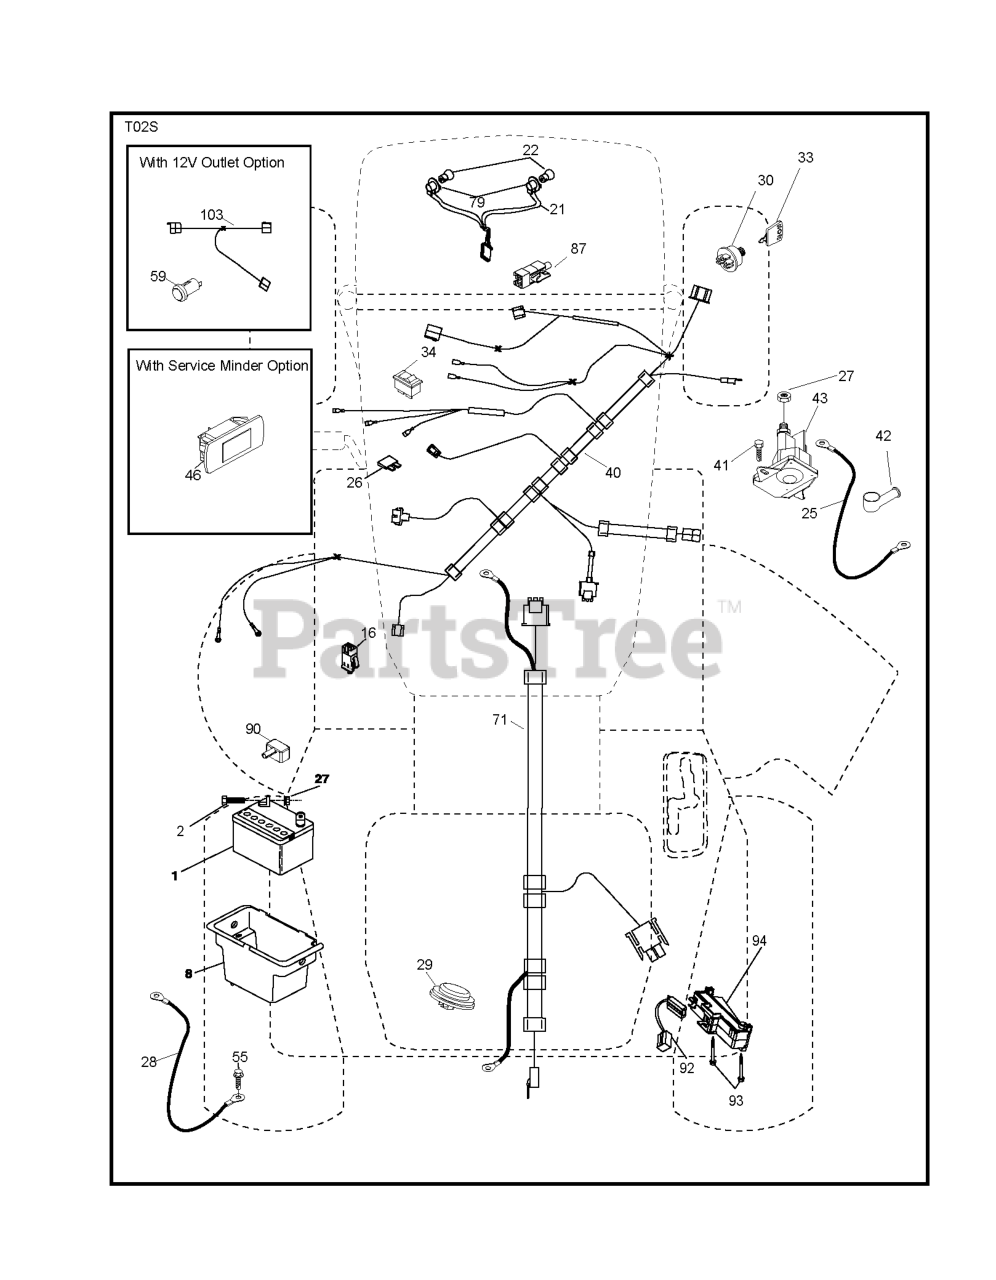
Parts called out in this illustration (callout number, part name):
1	Battery 12 Volt 25 Amp
2	BOLT.HEX.1/4.X.3/4.DICHROMATE
8	BOX.BATTERY.MNT.REAR.L
16	SWITCH INTERLOOK PUSH-IN
21	HARNESS.LIGHT W/4152J BULBS
25	CABLE.STARTER.6G.BL/RED.17.5
26	FUSE 20AMP
27	NUT
28	CABLE.BLACK.18"REAR.BA
29	SWITCH.SEAT.DELTA.OPC.
30	SWITCH.IGN.DELTA.W.LGH.ROS
33	KEY.CHAIN.BLISTER.PACK.GEN.INT
40	HARNESS IGN. DASH
41	SCREW
42	TERMINAL COVER
43	SOLENOID.W/BRASS.PLUNGER
55	SCREW 5/16"
71	HARNESS.IGN.CHASS.TEX.REAR.BAT
79	BULB HOLDER ASM.
87	SWITCH.INTRLCK.CLUTCH.
90	COVER, TERMINAL BATTERY
92	HARNESS.PIGTAIL.CONSLE
93	SCREW.PLASTITE
94	MODULE.REVERSE.ROS
